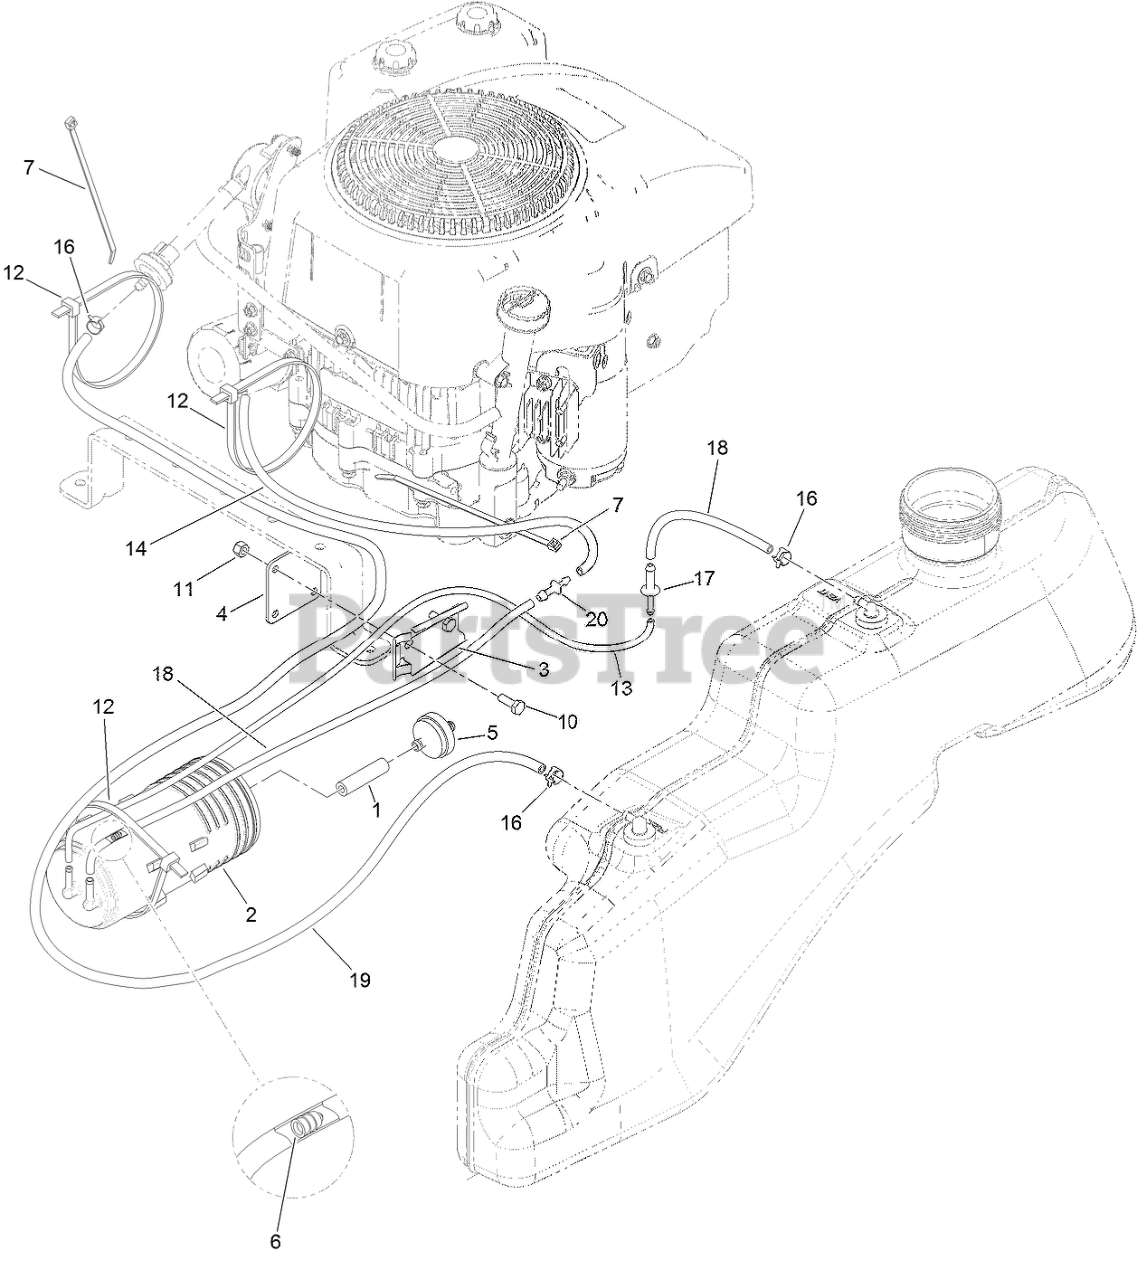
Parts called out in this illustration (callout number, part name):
1	HOSE-FUEL
2	CANISTER-CARBON, 800CC
3	BRACKET-CANISTER, CARBON
4	PLATE-ADAPTER
5	FILTER-FUEL, INLINE
6	CARTRIDGE-VALVE, CHECK
7	TIE-CABLE
10	SCREW-HH
11	NUT-LOCK, NI
12	TIE-CABLE
13	HOSE-FUEL
14	HOSE-FUEL
16	CLAMP-HOSE
17	ADAPTOR-ORIFICE
18	HOSE-FUEL
19	HOSE-FUEL
20	FITTING-STRAIGHT
